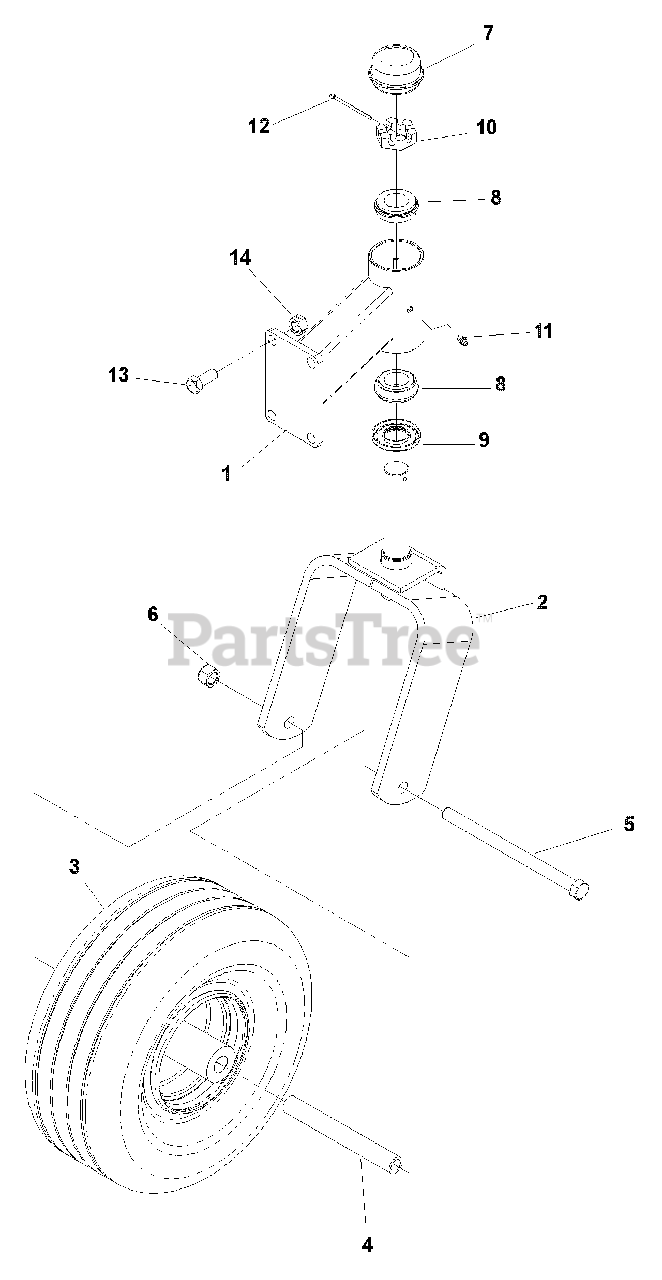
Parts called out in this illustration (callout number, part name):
1	CASTER ARM (ORANGE) 42" DECKS
1	CASTER ARM (ORANGE) 48" & 52" DECKS
2	CASTER YOKE
3	TIRE & WHEEL ASSEMBLY
3	TIRE
3	RIM
3	VALVE STEM
3	FLANGE BEARING
5	HCS 1/2-13 X 7 1/2
6	NUT 1/2C, NYLOC
7	GREASE CAP
10	NUT, 1"-14, SLOTTED JAM
12	PIN, COTTER, 1/8 X 2
13	HCS 7/16C X 1
14	NUT, 7/16C, LOCK
